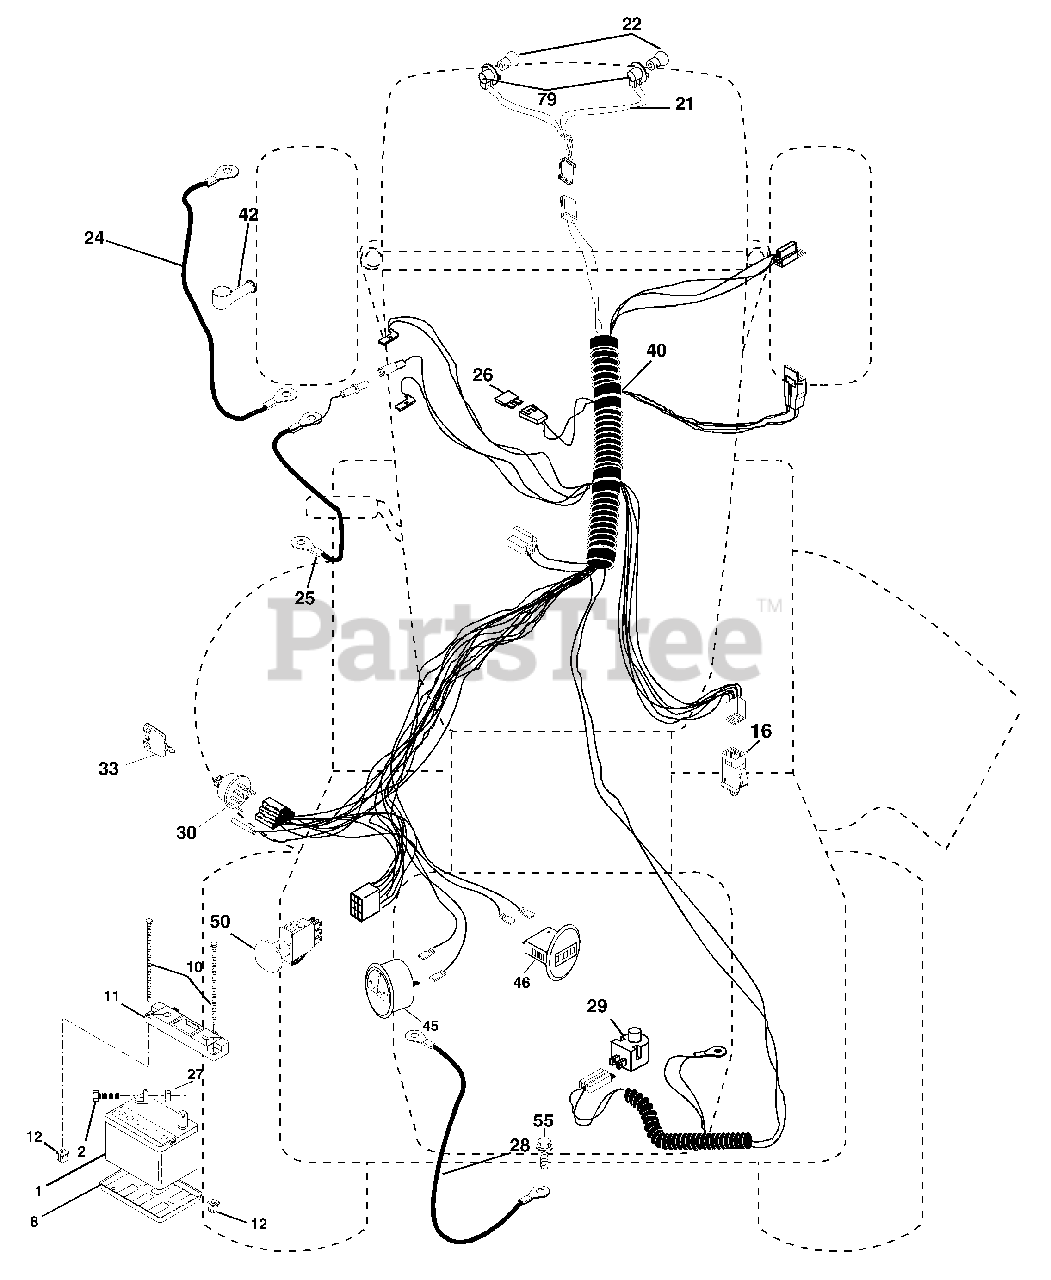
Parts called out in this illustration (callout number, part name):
1	Battery
2	Bolt Hex Hd 1/4-20 Unc x 3/4
8	Tray Battery 7.80 x 5.25
10	Bolt Btr Frt 1/4-20 x 7.5
11	Holddown Battery Front
12	Nut Push Nylon 1/4
16	Switch Interlock Push-In
21	Harness Asm Light W/4152J
22	Bulb Light #1156
24	Cable Battery 6 Ga 11"red
25	Cable Battery 6 Ga W/pos wire
27	Nut Keps Hex 1/4-20 Unc
29	Switch Plunger Normal Op Olive
30	Switch Ignition Delta Push-In
33	Key Ign Molded Generic Delta
42	Cover Terminal Red
45	Ammeter Round Delta
46	Hourmeter Round Delta
50	Switch PTO
55	Screw Thdrol 5/16-18 x 1/2
79	Bulb Holder Asm
